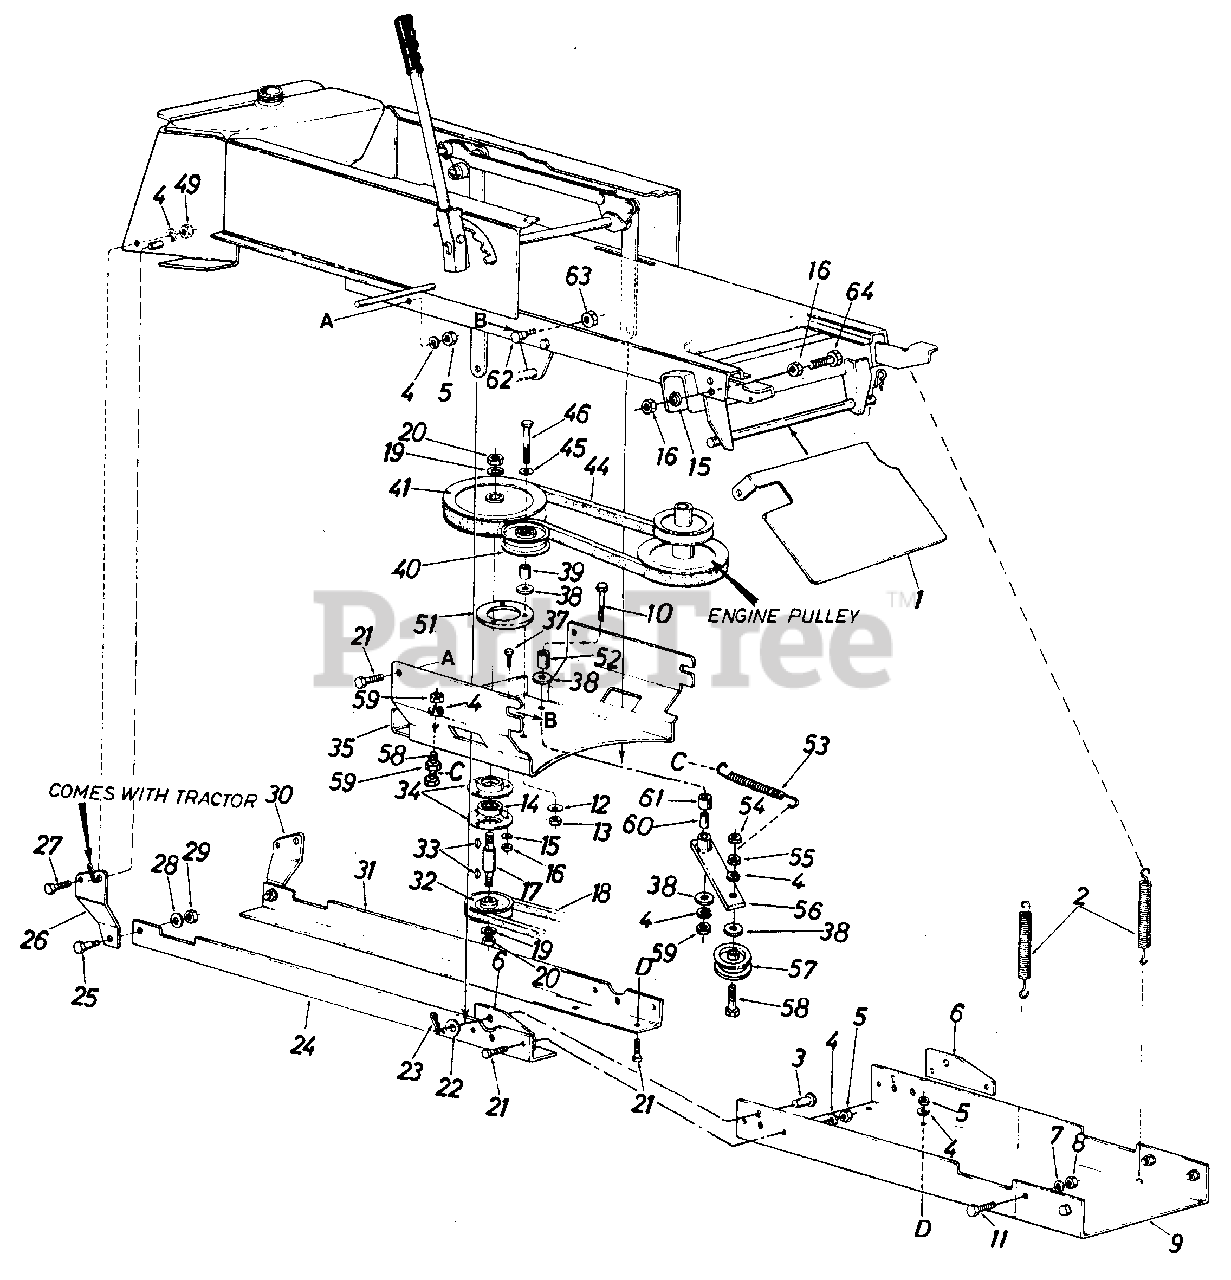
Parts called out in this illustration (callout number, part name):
1	Guide Bracket
2	Helper Spring
3	Clevis Pin
4	L.-Wash. 3/8" I.D.*
5	Hex L.-Nut3/8-24Thd.
6	Attaching Plate
7	L.-Wash. 1/2" I.D.*
8	Hex L.-Nut 1/2-20Thd.
9	Front Support Channel
10	Hex Bolt 3/8-16 x 3.75" Lg.
11	Hex Bolt 1/2-20x 1.25" Lg.*
12	Belleville Wash. 3/8" I.D.
13	Hex L.-Nut 3/8-16 Thd.
14	Ball Bearing
15	L.-Wash. 5/16" I.D.*
16	Hex Nut 5/16-18 Thd.*
18	"V"-Belt 1/2" x88"x 2 (Kevlar)
19	L.-Wash. 5/8" I.D.*
20	Hex Jam Nut 5/8-11 Thd.
21	Hex Bolt 3/8-24 x 1.00" Lg.*
23	Internal Cotter Pin
28	Fl.-Wash. .44" I.D. x 1.38" O.D. x .130
29	Hex L.-Nut 7/16-24 Thd.
30	Rear Hanger Brkt.-L.H.
33	#6 Hi-Pro Key 3/16 x 5/8" Dia.
34	Bearing Housing
35	Supporting Bracket
37	Hex Sems Bolt 5/16-18 x 1.00" Lg. *
38	Fl.-Wash. .38" I.D. x 1.00" O.D. x .135
39	Spacer .38" I.D. x .62" O.D.
40	Fl.-ldler Pulley
41	Upper Drive Pulley
44	"V"-Belt 1/2" x 49.8" Lg.
46	Hex Bolt 3/8-16 x 2.50" Lg.*
49	Hex Nut 3/8-16 Thd.*
53	Extension Spring .54" O.D. x 4.75" Lg.
54	Hex Cent. L.-Nut 3/8-16 Thd.
55	Hex Jam Nut 5/8-11 Thd.
56	Idler Arm Ass'y.
57	Idler Pulley
58	Hex Bolt 3/8-16 x 2.25" Lg.
59	Hex Jam Nut 3/8-16 Thd.
60	Spacer.377" I.D. x .60" O.D. x.830" Lg.
61	Spacer.380" I.D. x .630" O.D. x.565" Lg.
62	Shoulder Bolt .498 Dia. x .340
63	Hex Cent. L.-N ut 3/8-16 Thd.
64	Hex Bolt 5/16-18 x1.50" Lg.*
